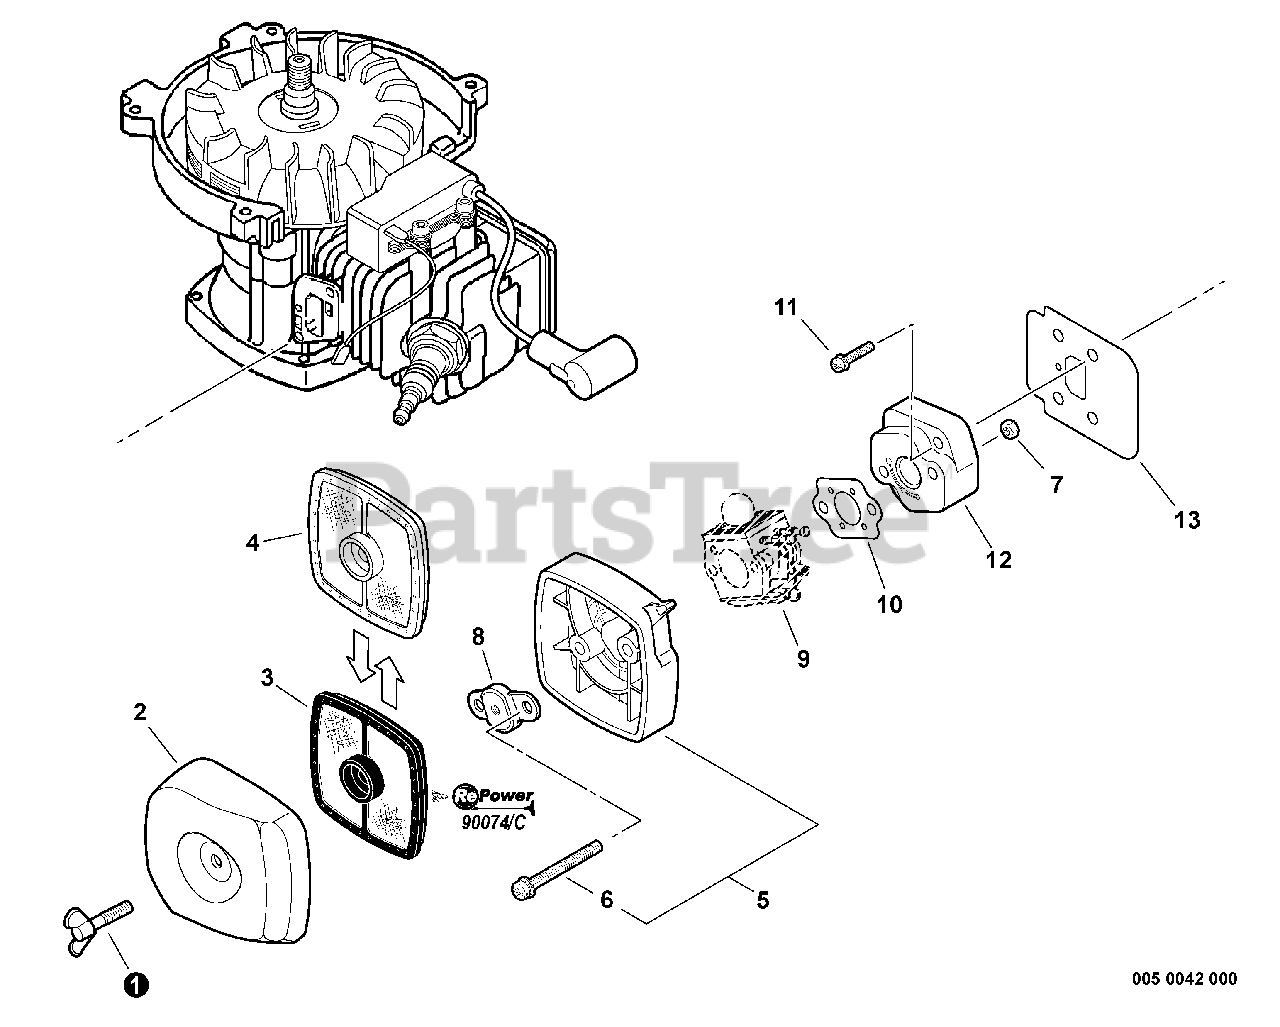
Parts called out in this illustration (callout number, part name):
1	THUMBSCREW
2	COVER, AIR FILTER - GRAY
2	COVER, AIR FILTER - BLACK
3	FILTER, AIR - DOUBLE LAYER
4	FILTER, AIR - SINGLE LAYER
5	AIR FILTER CASE KIT - GRAY
5	AIR FILTER CASE KIT - BLACK
6	SCREW - 5X65
8	PLATE, PREVENT
9	CARBURETOR
10	GASKET, INTAKE
11	SCREW - 5X20
12	INSULATOR, INTAKE
13	SHIELD, INTAKE
14	RePower TUNE-UP KIT
